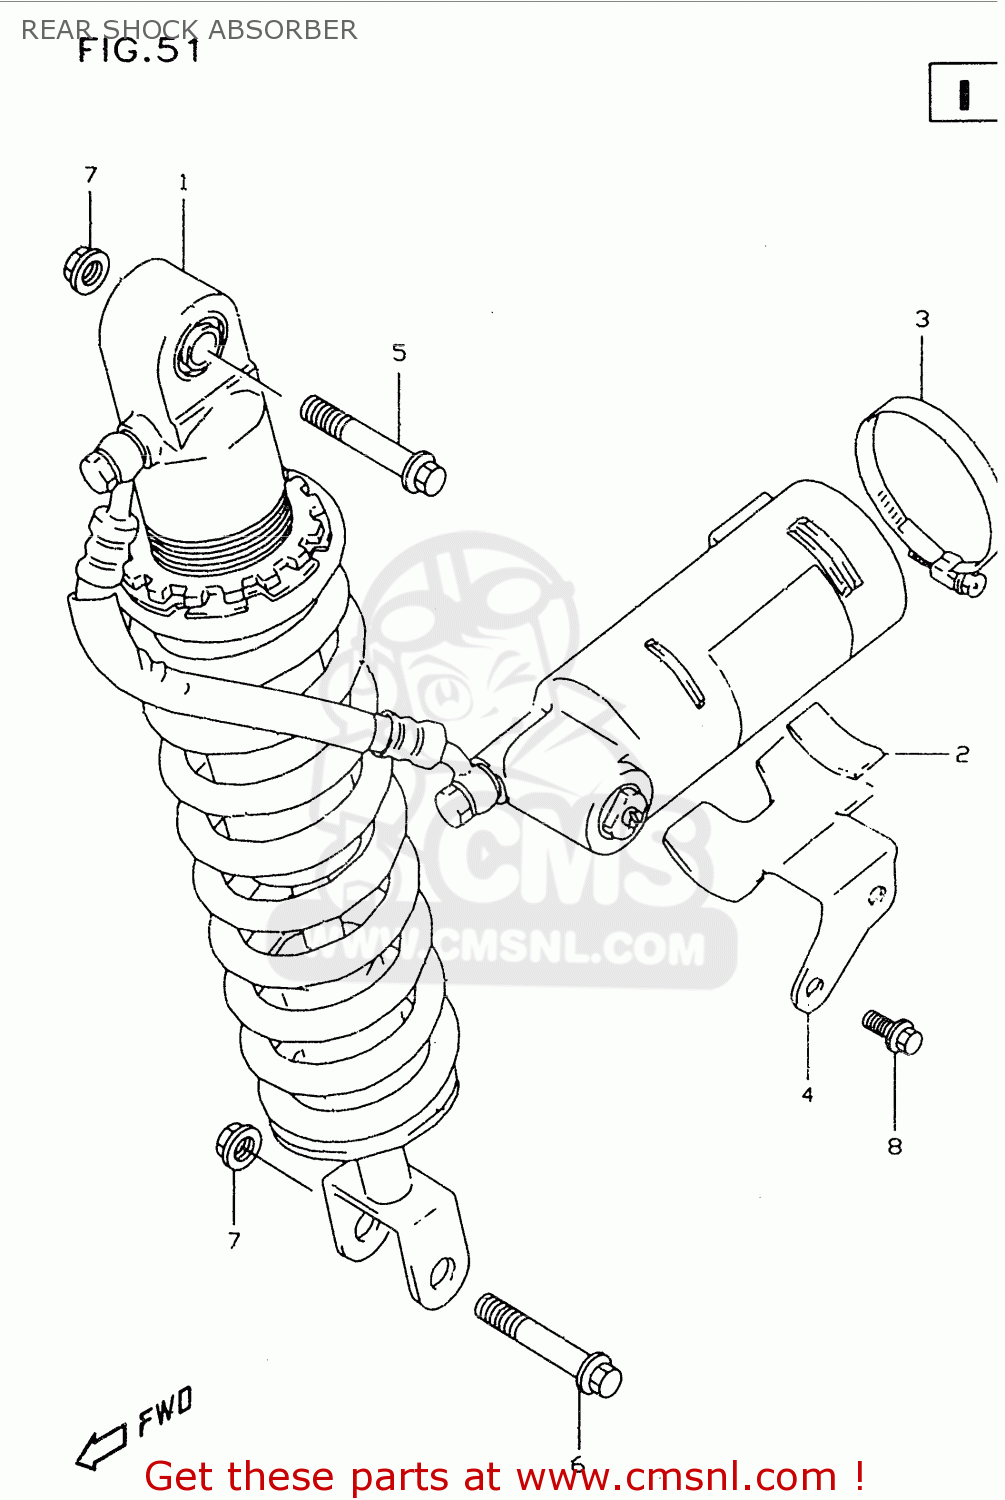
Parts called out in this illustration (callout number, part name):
1	ABSORBER ASSY,RR SHOCK
2	CUSHION
3	CLAMP
4	BRACKET,RESERVOIR TANK
5	BOLT,RR SHOCK ABSORBER
6	BOLT,RR CUSHION ROD UPR
7	NUT
8	BOLT
